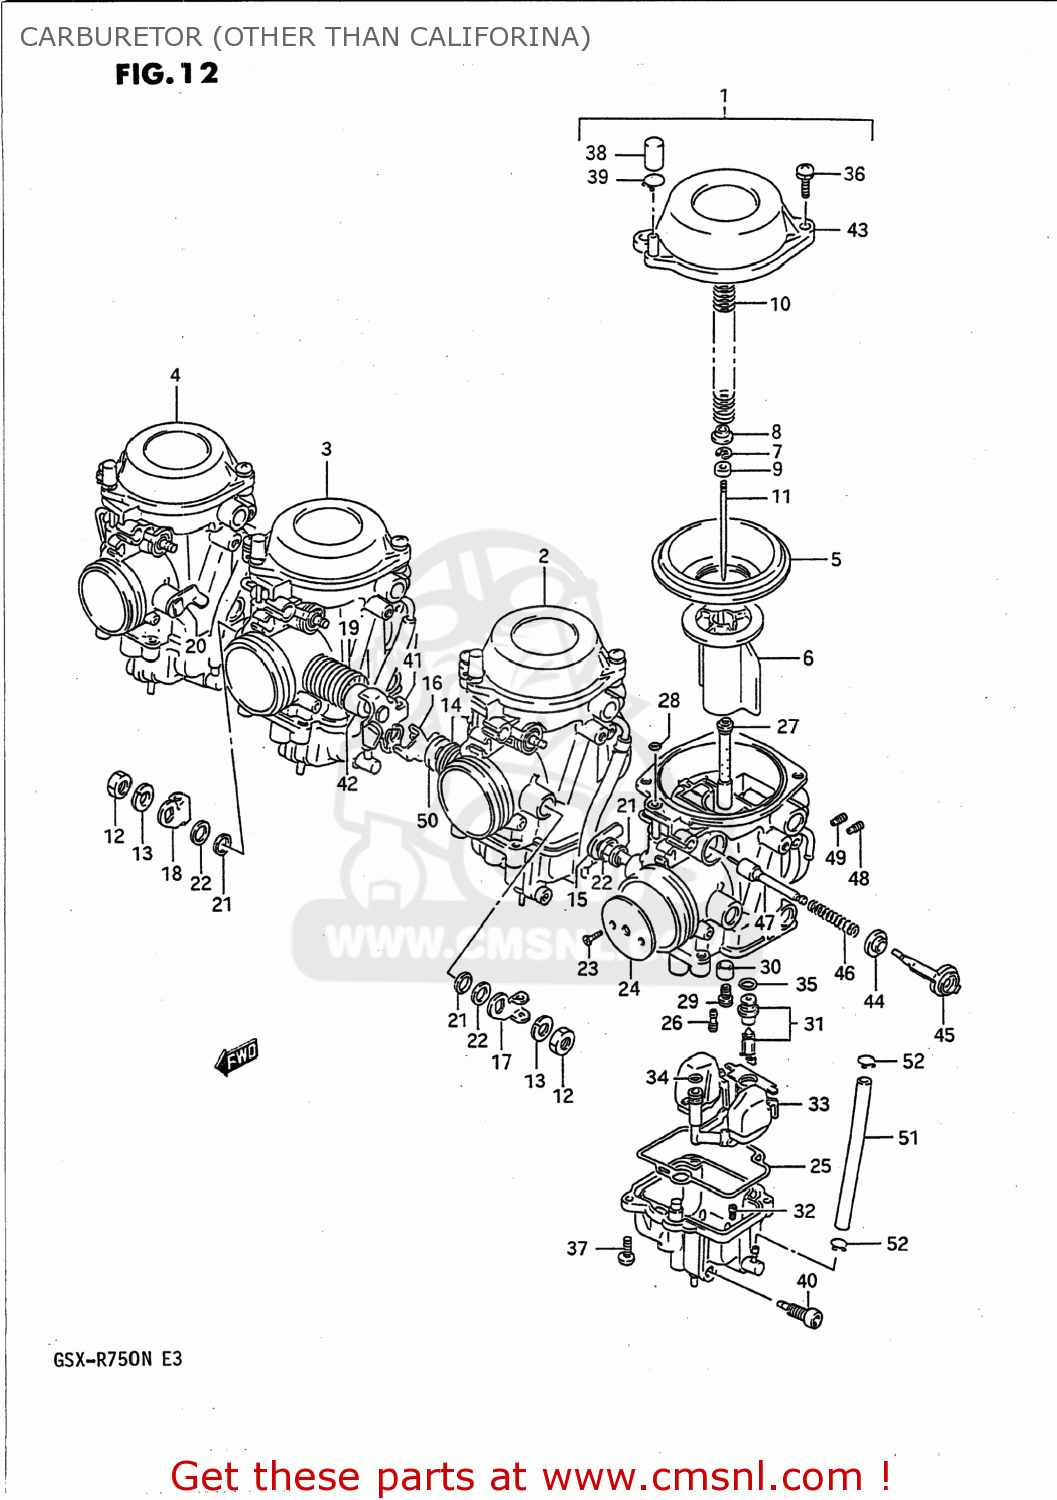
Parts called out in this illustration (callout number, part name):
1	CARBURETOR ASSEMBLY,LEFT
2	CARBURETOR ASSEMBLY,MIDDLE,LEFT
3	CARBURETOR ASSEMBLY,MIDDLE,RIGHT
4	CARBURETOR ASSEMBLY,RIGHT
5	DIAPHRAGM
6	VALVE,PISTON
7	CLIP,NEEDLE
8	WASHER
9	RING
10	SPRING
11	NEEDLE JET
12	NUT
13	WASHER,LOCK,8.
14	SPRING
15	SHAFT ASSEMBLY
16	SHAFT ASSEMBLY
17	LEVER
18	LEVER,THROTTLE
19	SPRING
20	SHAFT ASSEMBLY
21	SEAL
22	GASKET,THROTTLE SHAFT (NAS)
23	SCREW
24	VALVE,THROTTLE
25	GASKET,FLOAT CHAMBER (NAS)
26	JET,PILOT(32.5)
27	JET,NEEDLE(O-8)
28	O RING
29	JET,MAIN(127.5)
30	RING
31	VALVE ASSEMBLY,NEEDLE
32	PLUG
33	FLOAT ASSY
34	O RING
35	O-RING,NEEDLE VALVE
36	SCREW
37	SCREW
38	CAP
39	CLIP
40	PLUG,DRAIN
41	SHAFT ASSEMBLY
42	RING
43	COVER,DIAPHRAGM
44	CAP,STARTER
45	HOLDER,GUIDE
46	SPRING
47	PLUNGER ASSY
48	JET,AIR(1.2)
49	JET,AIR(1.25)
50	RING
51	HOSE
52	CLIP
